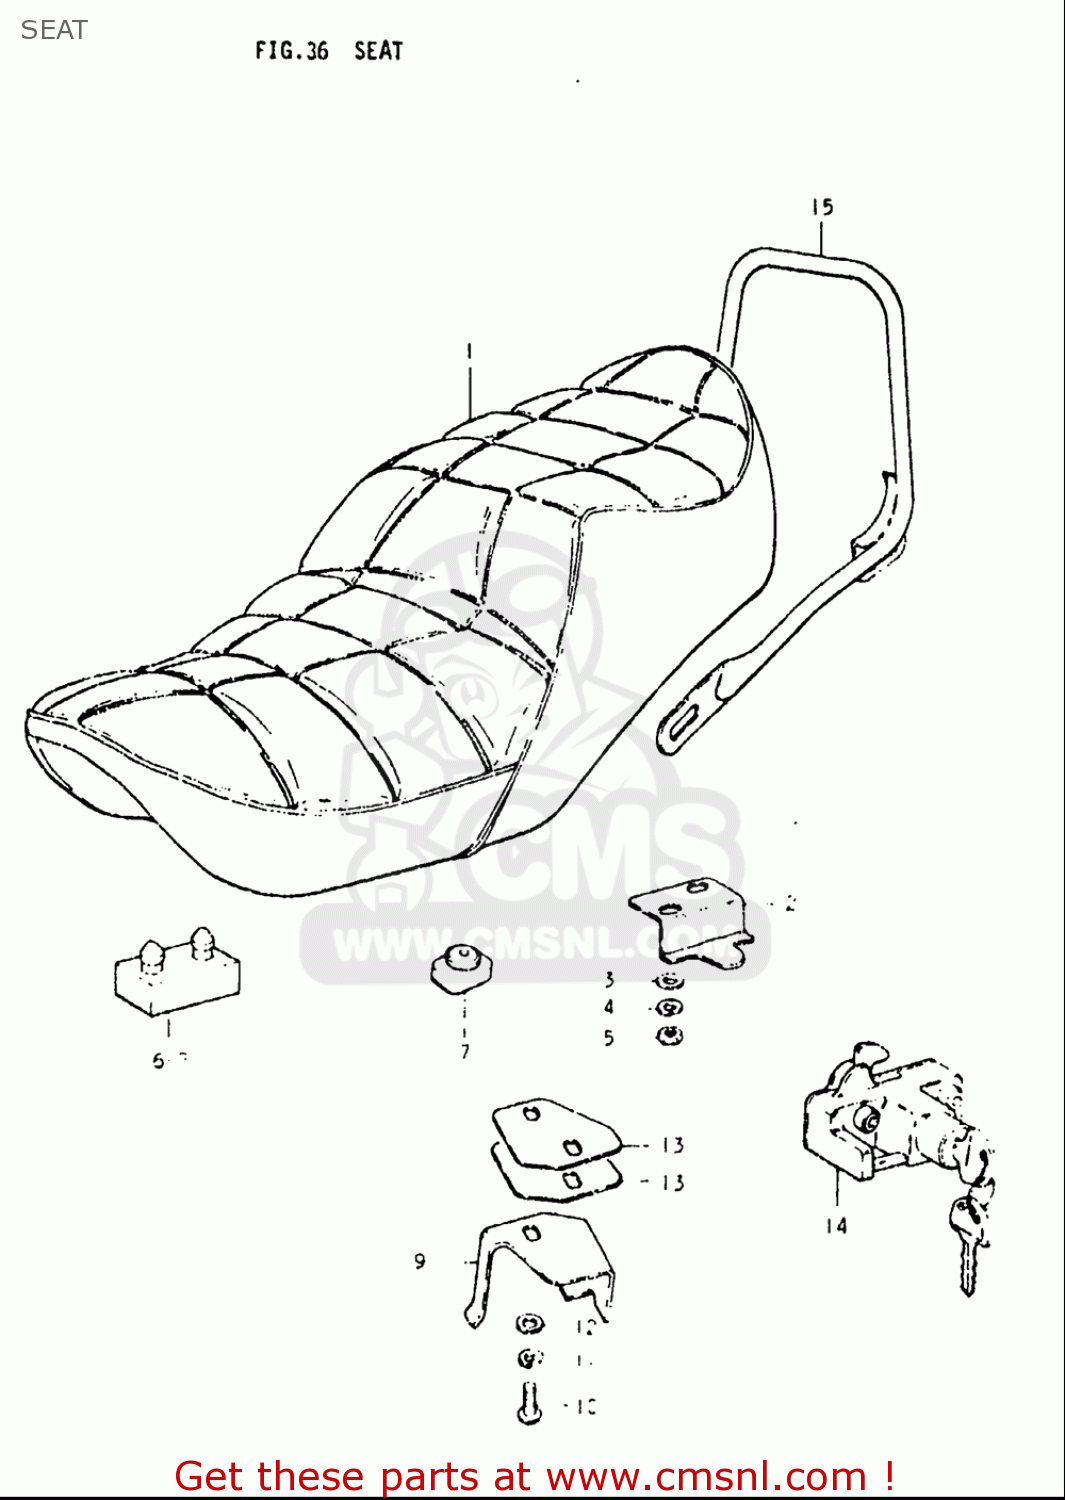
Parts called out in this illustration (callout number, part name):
3	WASHER
4	WASHER,LOCK
5	NUT
6	CUSHION
7	CUSHION
8	CUSHION
10	BOLT
11	WASHER,LOCK
12	WASHER(6.5X16X1.2)
